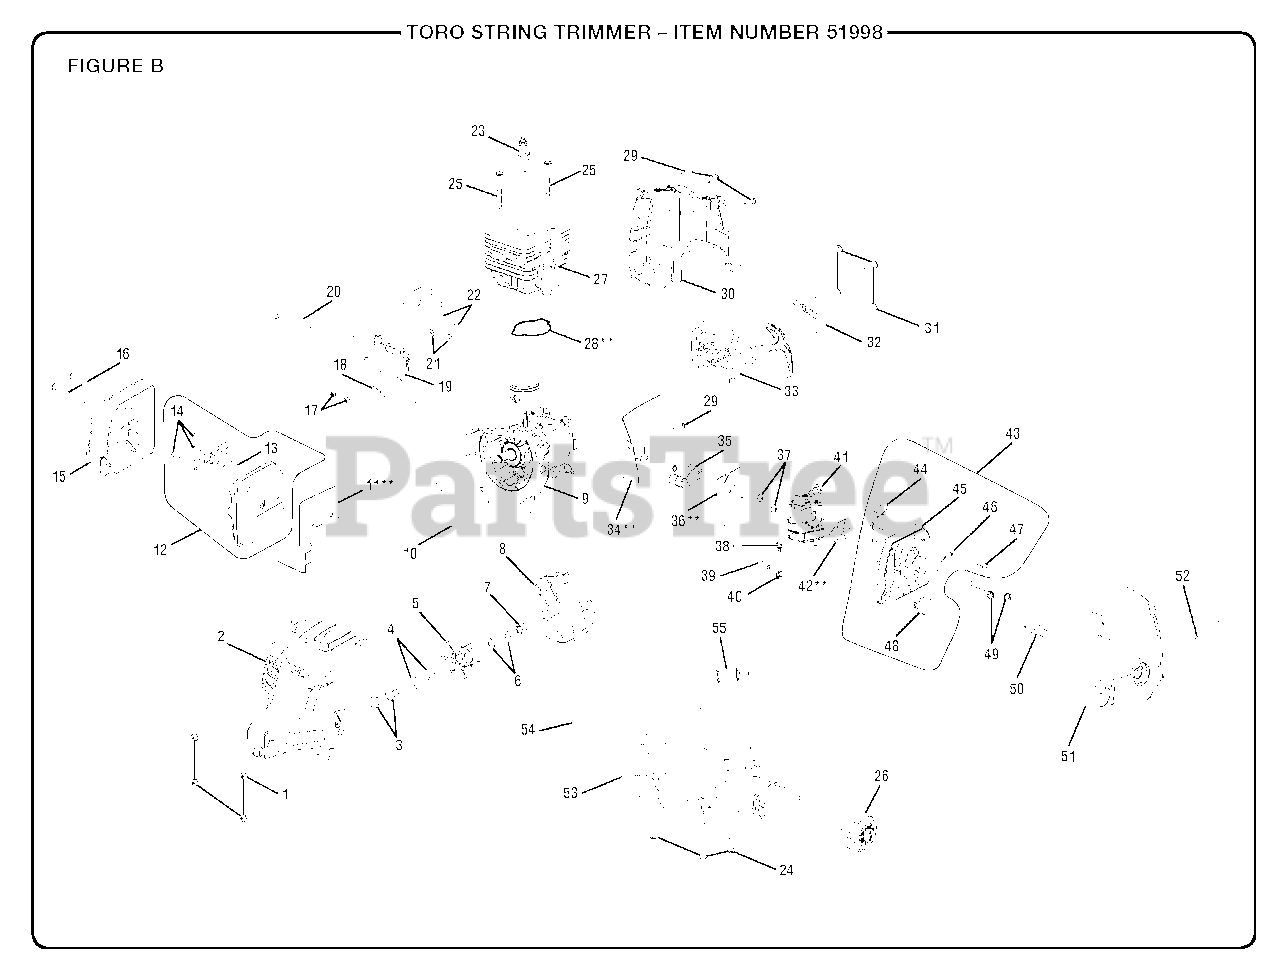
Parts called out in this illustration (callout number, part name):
1	Screw (M5 x 20 mm, T20 Torx Pan Hd.)
2	Front Housing Assembly
3	Clutch Shoulder Bolt (M6 x 22.5 mm, Hex Hd.)
4	Curved Washer
5	Clutch Assembly
6	Washer (ID6 x OD15 x 1.2t)
7	Flywheel Nut
9	Crankcase Assembly
10	Woodruff Key (10 mm x 3 mm)
11	Muffler Gasket
12	Muffler Assembly
13	Screen
14	Screw (6-20 x 1/4 in., T20 Torx Pan Hd. S.T.)
15	Heat Shield
16	Screw (M5 x 50 mm, T25 Torx Soc. Hd.)
17	Screw w/Washer (M4 x 19 mm, T20 Torx Soc. Hd.)
18	Lead Wire (Red)
19	Coil Boot Assembly
20	Lead Wire (Black)
21	Washer (ID4.2 x OD10 x1t)
22	Spacer (Phenolic)
23	Spark Plug (Champion RCJ4)
24	Screw (M5 x 16 mm, T25 Torx Soc. Hd.)
25	Screw (M5 x 22 mm, T25 Torx Soc. Hd.)
26	Fuel Cap Assembly
28	Gasket
29	Screw (M4 x 18 mm, T20 Torx Pan Hd. S.T.)
30	Rear Engine Housing
31	Screw w/Washer (M5 x 16 mm, T25 Torx Soc. Hd.)
32	Logo Label (Rear)
33	Starter Recoil & Starter Cup Assembly
34	Insulator Gasket
35	Heat Dam Insulator
36	Gasket
37	Screw w/Washers (M5 x 34 mm, T25 Torx Pan Hd.)
38	Hose Clip
39	Fuel Line (45 mm)
40	Hose Clip
41	Carburetor Assembly
42	Carburetor Gasket
43	Airbox Base Assembly
44	Choke Lever
45	Airbox Base
46	Choke Plate
47	Screw (M4 x 12 mm, T20 Torx Pan Hd. S.T.)
48	Primer Assembly
49	Screw (M5 x 60 mm, T25 Torx Cap Soc. Hd.)
50	Air Filter
51	Airbox Cover Assembly w/Label
52	Starting Instructions Label
53	Fuel Tank & Cap Assembly
54	Combustion Warning Label
55	Fuel Filter
